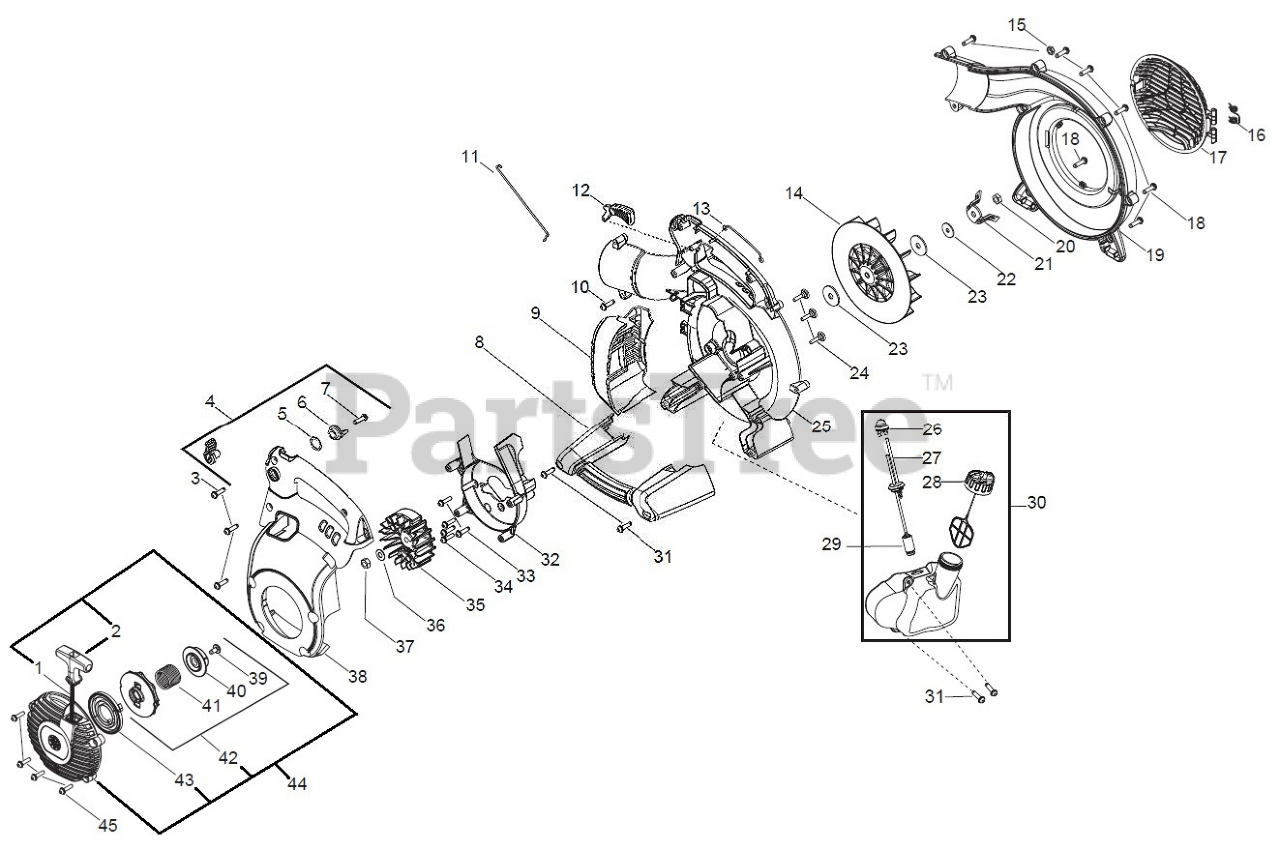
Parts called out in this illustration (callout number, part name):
1	KIT ROPE
2	STARTER HANDLE
3	SCREW
4	KIT CRUISE CONTROL
5	WAVE WASHER
6	RATCHET CRUISE CONTROL
7	SCREW
8	HANDLE ASSIST W/OVER MOLD
9	ASSY, MUFFLER GUARD
10	SCREW
11	WIRE LINKAGE
12	TRIGGER, THROTTLE
13	WIRE, HANDLE GROUND
15	NUT
16	SPRING, VAC DOOR
17	COVER VAC DOOR
18	SCREW
19	OUTER SCROLL ASSY VAC
20	NUT, IMPELLER
23	WASHER IMPELLER
24	SCREW FUEL TANK RETAINER
25	SCROLL - INNER
26	AIR PURGE
27	FUEL LINE GROMMET KIT
29	FUEL PICK-UP ASSY
31	SCREW
33	SCREW
34	SCREW FUEL TANK RETAINER
35	FLYWHEEL ASSY
36	WASHER FLAT
37	NUT-FLYWHEEL
38	COVER - MOTOR HOUSING
39	SCREW
40	HUB
41	SPRING EPS2
42	KIT - STARTER
43	SPRING STARTER
44	HOUSING - STARTER COVER
45	SCREW
